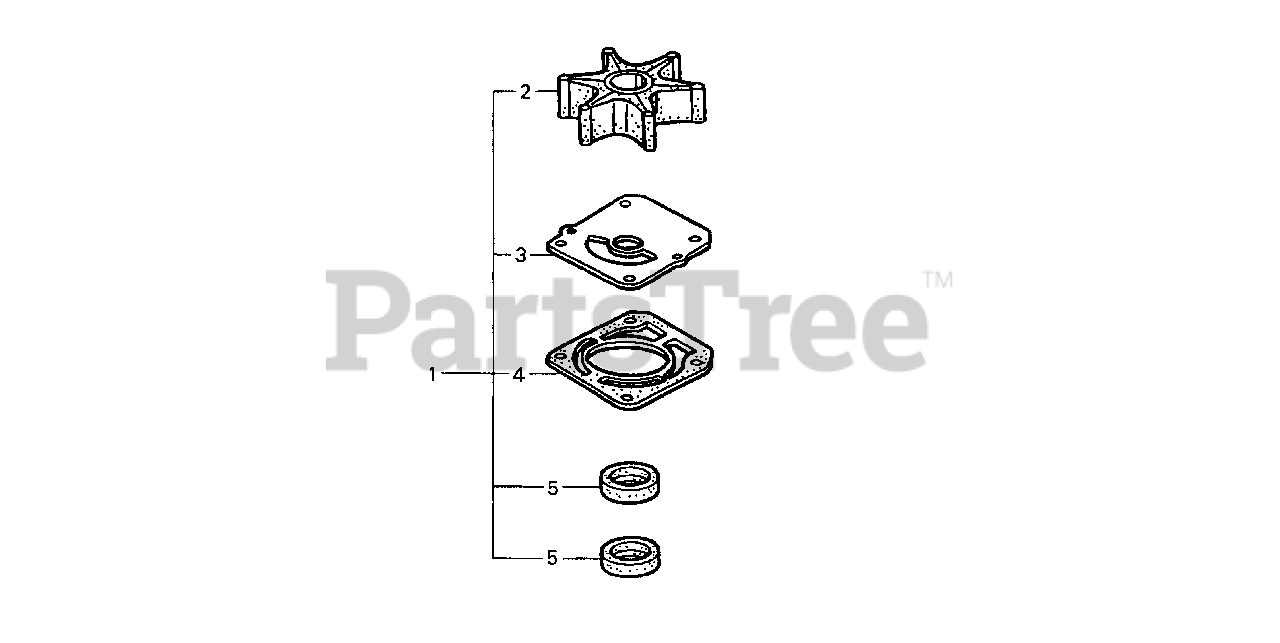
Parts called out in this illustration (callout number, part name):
1	IMPELLER KIT, WATER PUMP Use up to Frame SN 1102290.
1	IMPELLER KIT, WATER PUMP
2	IMPELLER, PUMP
3	GASKET B, IMPELLER
4	GASKET, WATER PUMP
5	SEAL, WATER (23X36X6) Use up to Frame SN 1102290.
5	SEAL, WATER (23X36X6)
